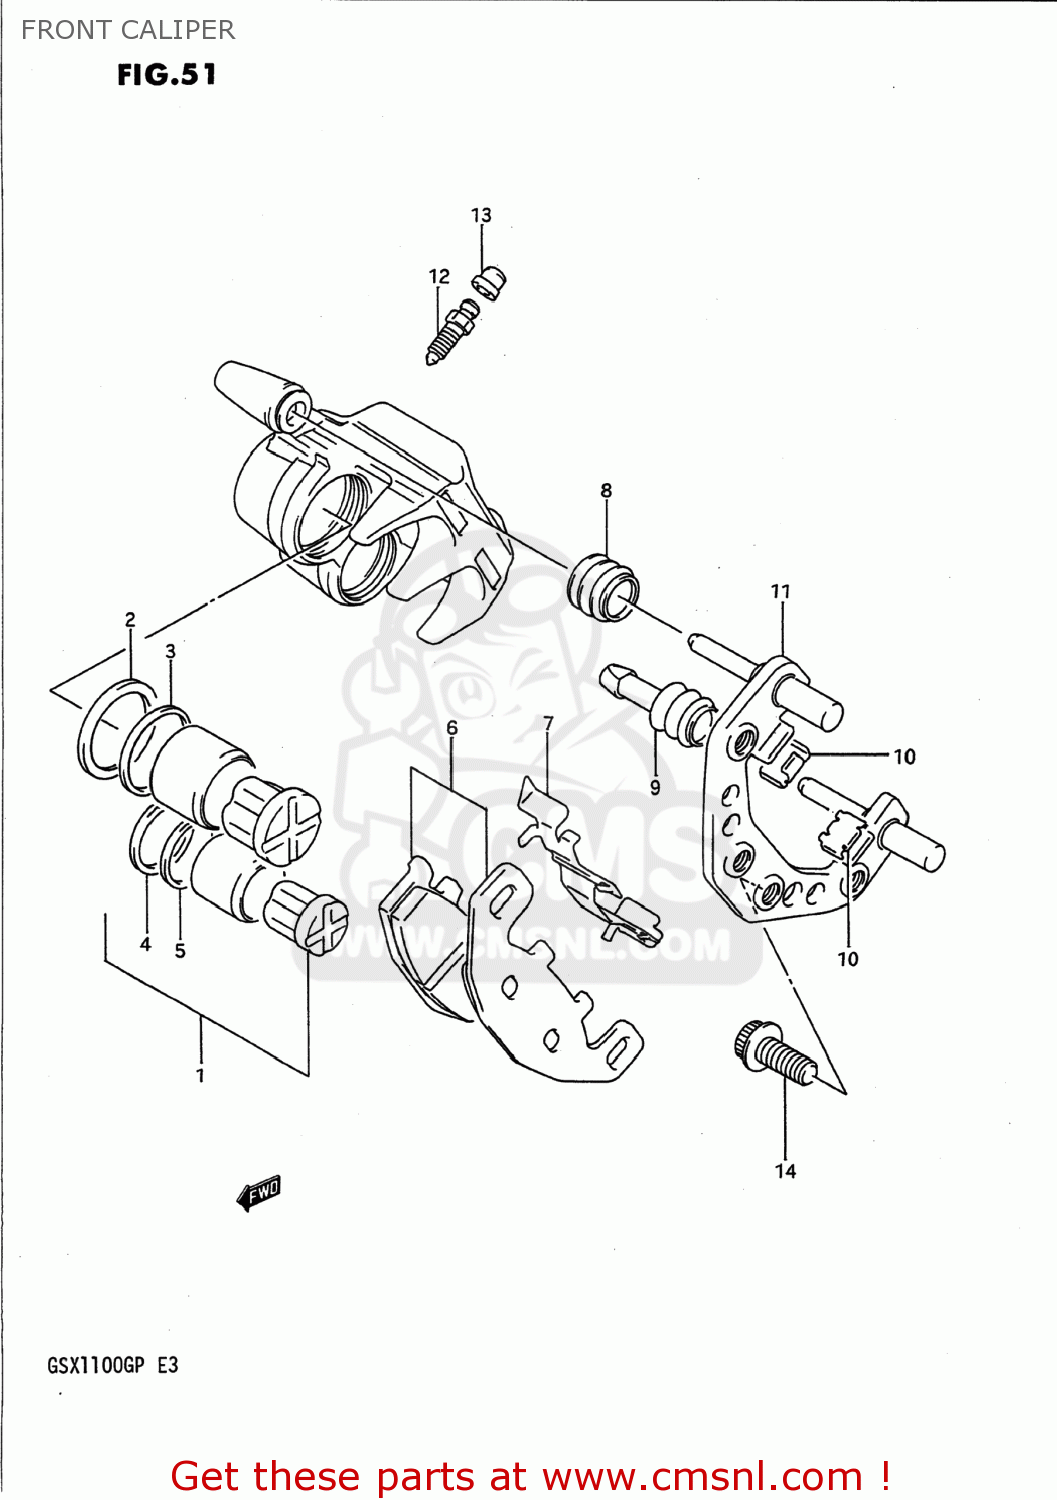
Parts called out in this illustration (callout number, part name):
1	PISTON SET
2	SEAL,PISTON
3	SEAL,WIPER
4	SEAL,PISTON
5	SEAL,WIPER
6	PAD SET (NAS)
7	SPRING,PAD
8	BOOT,AXLE
9	INSULATOR,AXLE
10	GUIDE,PAD
11	CARRIER,CALIPER
12	BLEEDER
13	CAP,BREATHER
14	BOLT
